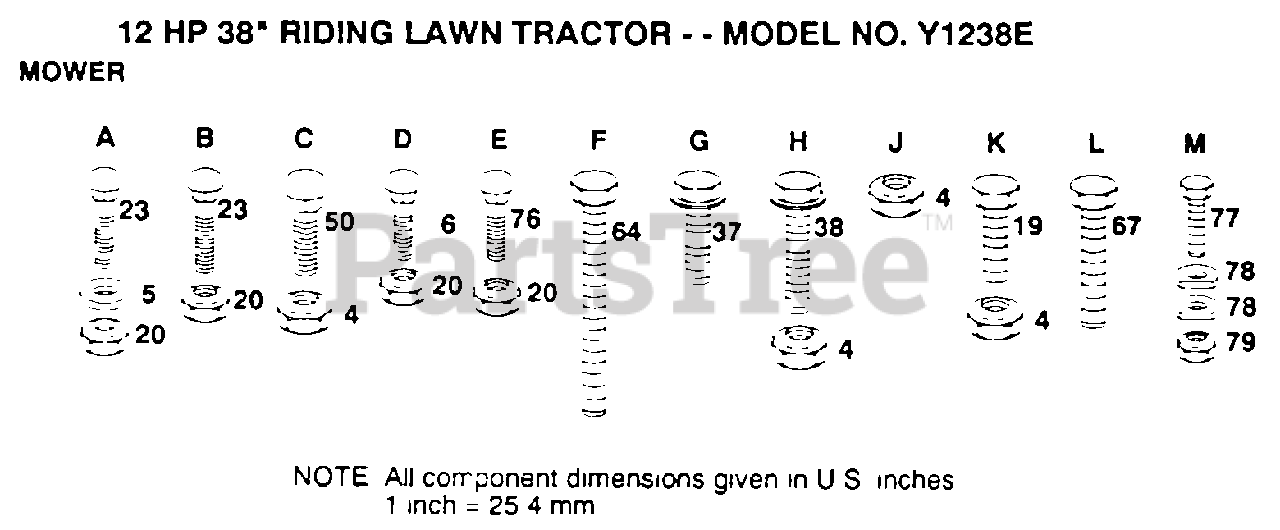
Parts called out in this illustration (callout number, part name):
5	WASHER M
6	BOLT
23	BOLT
37	SCREW
38	SCREW
50	BOLT
64	BOLT
67	BOLT.3/8-14X1.25
77	BOLT LT
78	WASHER T
